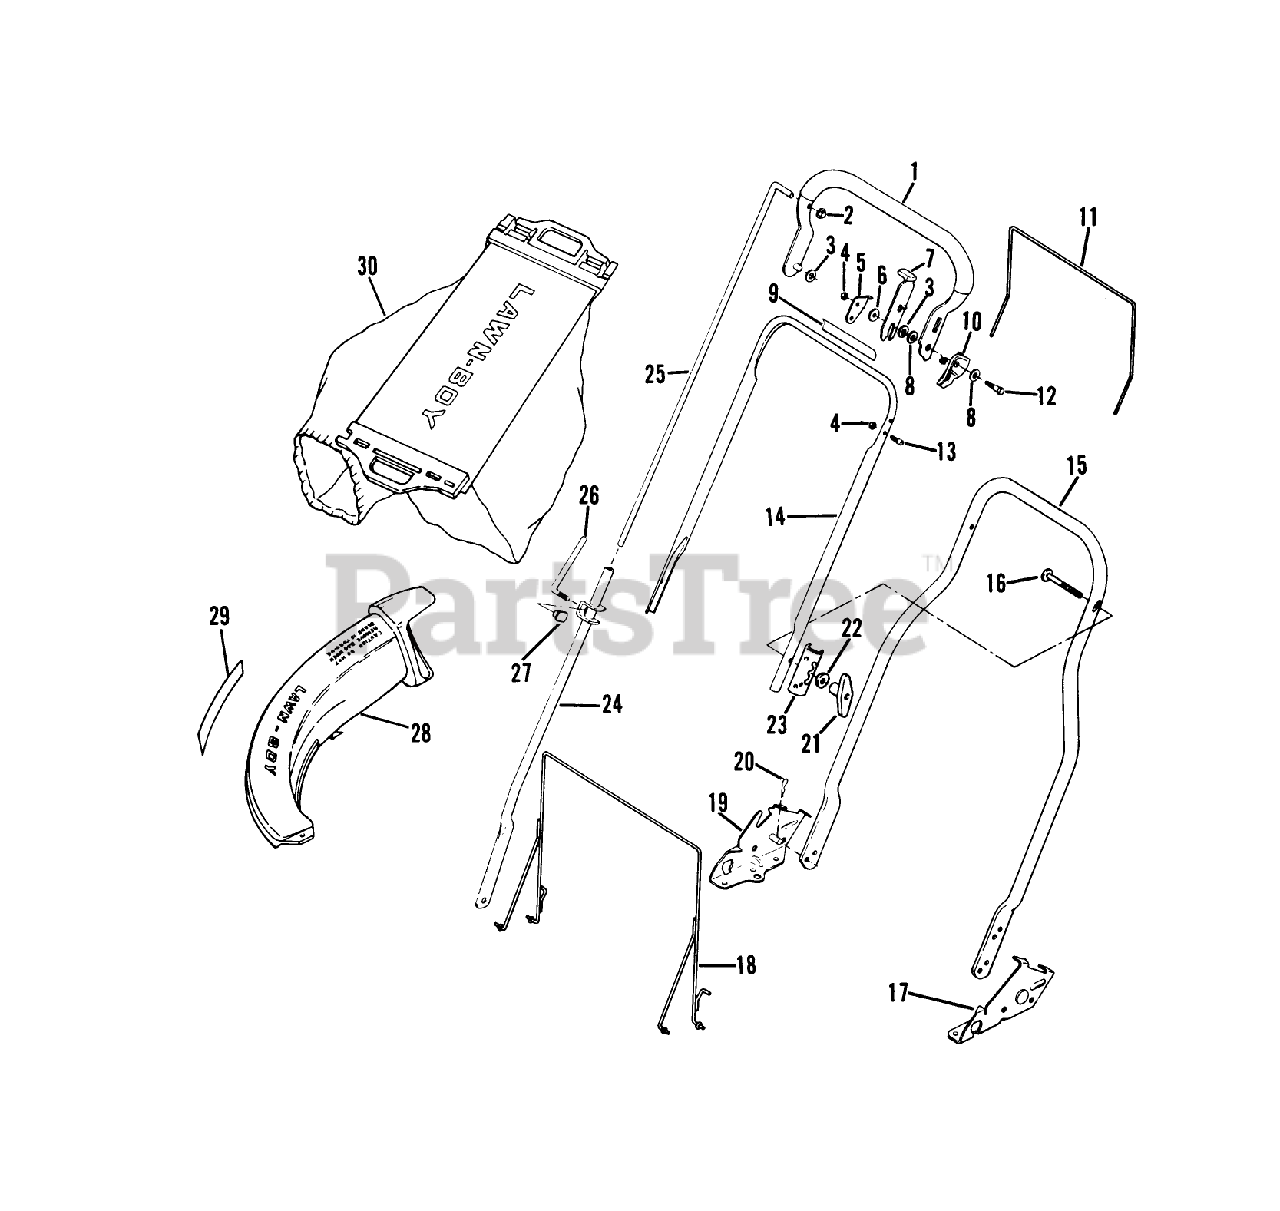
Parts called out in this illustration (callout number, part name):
3	WASHER M
4	LOCKNUT E
5	HANDLE STOP
6	WASHER
7	LEVER LOCKOUT
11	HANGER
12	BOLT PIONEER
13	SCREW-HANDLE STOP
14	HANDLE
19	HANDLE BRACKET
20	HAIR PIN
21	NUT-WING
22	WASHER-CURVED
23	BRACKET R/B 613462
25	ROD CONTROL
